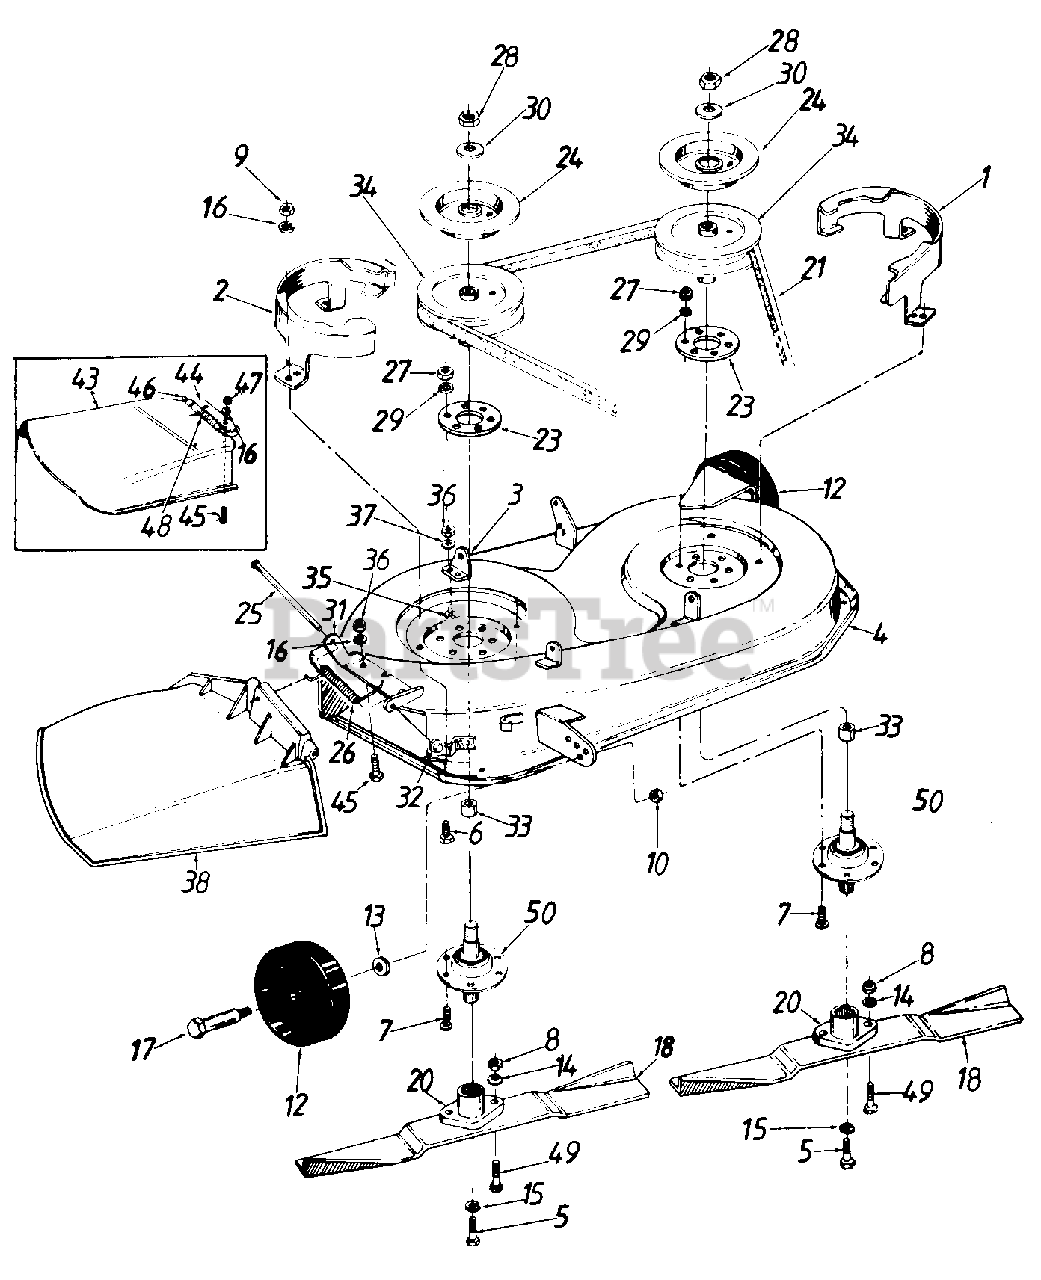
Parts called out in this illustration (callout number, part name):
5	Hex Bolt 3/8-24 x 1.0" Lg.
6	Hex Bolt 1/4-28 x .62" Lg.
7	Rib Neck Bolt
8	Hex Nut 5/16-24 Thd.
9	Hex Nut 1/4-28 Thd.
10	Hex L-Nut 3/8-16 Thd.
12	Deck Wheel
13	Bell-Wash. .380" I.D. x .88
14	L-Wash. 5/16" I.D.
15	L-Wash. 3/8" I.D. H.D.
16	Bell-Wash. .265" I.D. x .75
17	Shld. Bolt .498" Dia. x 1.53
18	High-Lift Blade
20	Blade Adapter
21	V-Belt
24	Brake Disc
25	Hinae Pin
26	Torsion Spring
27	Hex Nut 5/16-24 Thd.*
28	Hex Jam Nut 5/8-18 Thd.
29	L-Wash. 5/16" I.D.
30	L-Wash. 5/8" I.D.
31	Hinge Mtg. Brkt.
32	Push Nut
33	Spacer
34	5" Dia. Pulley
35	Hex Scr. 1/4-20 x .62" Lg.
36	Hex Nut 1/4-20 Thd.
37	L-Wash. 1/4" I.D.
38	Chute Ass'y. Comp. (Plastic)
43	Chute Ass'y. (Steel)
44	Chute Bracket (Steel)
45	Truss-Mach. Scr. 1/4-20 x .75" Lg.
46	Hinge Pin
47	Hex Jam Nut 1/4-20 Thd.
48	Torsion Spring 1.14" Lg.
49	Hex Bolt 5/16-24 x 1.0" Lg.
50	Blade Spindle Complete
